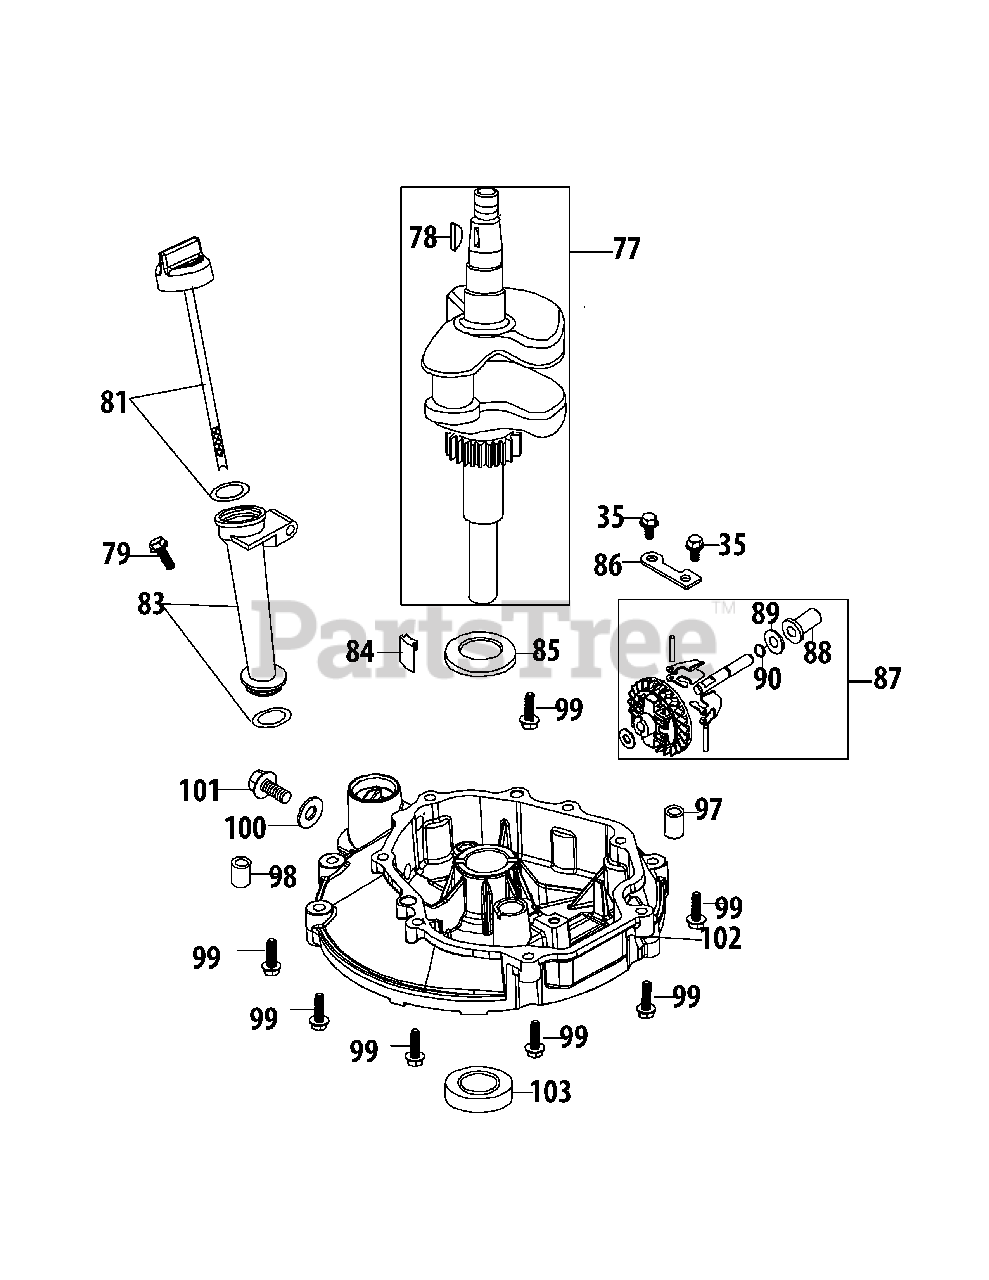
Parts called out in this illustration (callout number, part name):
35	Bolt M6X14 Multi-Purpose
77	Crankshaft Assembly
78	Flywheel Key
79	Bolt M6X35 Af Base/Brake/Dipstick
81	Dipstick
83	Oil Fill Tube
84	Oil Return Seal
85	Crankshaft Thrust Washer
86	Governor Gear Mounting Plate
87	Governor Gear/Shaft Assembly
88	Governor Slide Cap
89	Governor Slide Cap Washer
90	Governor Shaft Stop Ring
97	Crankcase Cover Dowel Pin 07×14
98	Crankcase Cover Dowel Pin 09×14
99	Bolt M6X28 T/X/P Multi-Purpose/Crankcase
100	Oil Drain Plug Washer
101	Oil Drain Plug
102	Crankcase Cover
103	Lower Crankshaft Seal
